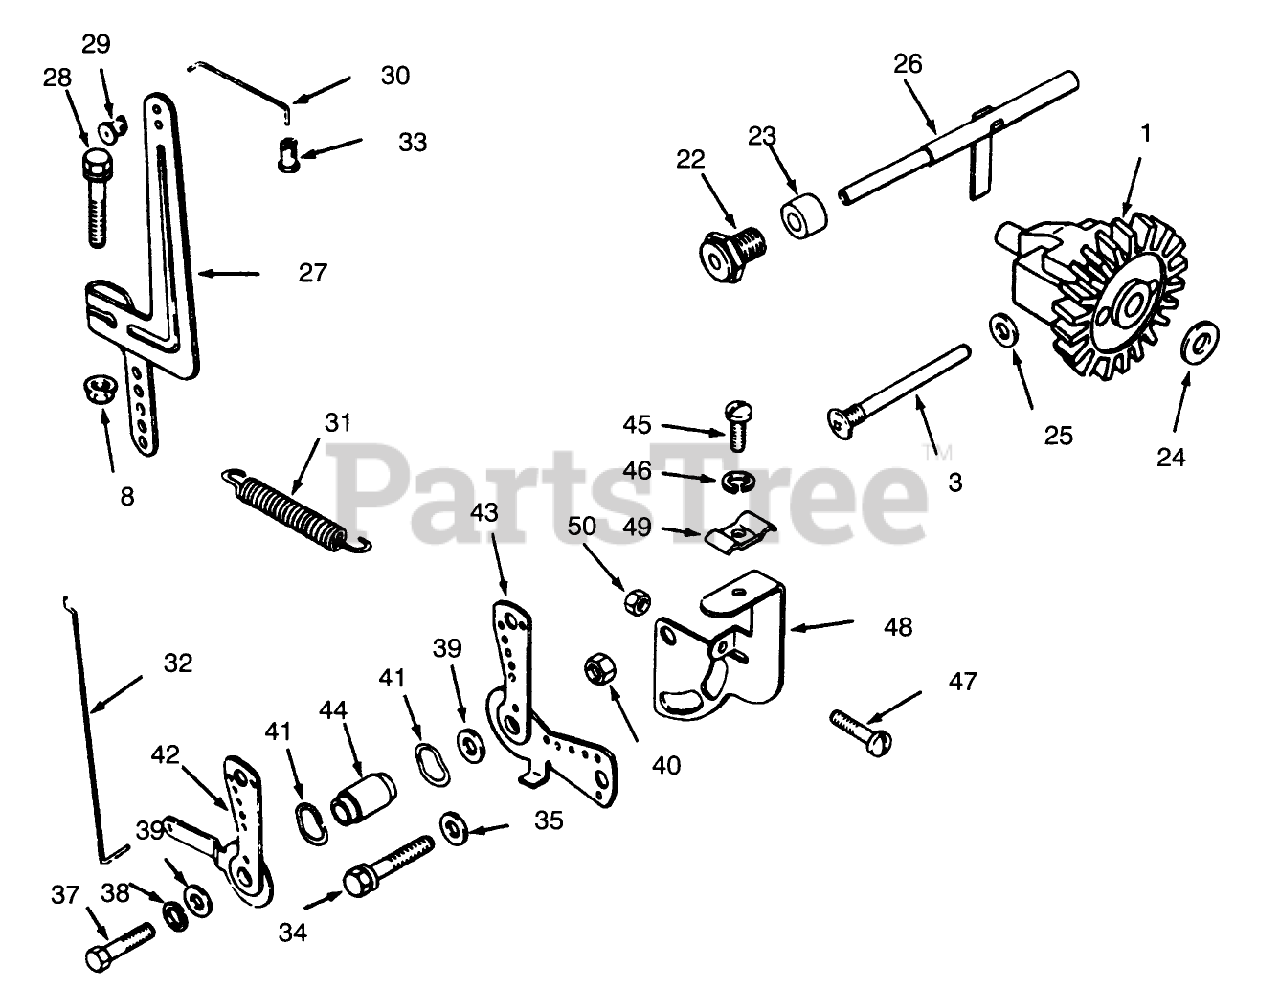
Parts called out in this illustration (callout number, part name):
1	KOHLER A-235743-5
3	KOHLER 231355
8	KOHLER X-799-1
22	KOHLER 235476
23	KOHLER X-400-80
24	KOHLER 237022
25	KOHLER 25-468-01
26	VNDR #A-235256-S
27	KOHLER 47-090-20
28	KOHLER X-776-1
30	KOHLER 47-079-10
31	KOHLER 47-091-01
32	KOHLER 47-079-01
34	KOHLER X-132-6
35	KOHLER X-25-72
37	KOHLER X-5-26
38	KOHLER X-20-1
39	KOHLER X-25-63
40	KOHLER X-76-2
41	KOHLER 275690
42	KOHLER 47-090-07
43	KOHLER 47-090-08
44	KOHLER 47-112-02
45	KOHLER X-67-51
46	KOHLER 25-468-04
47	KOHLER 232556
48	KOHLER 47-126-09
49	KOHLER 47-237-02
50	KOHLER X-72-4
